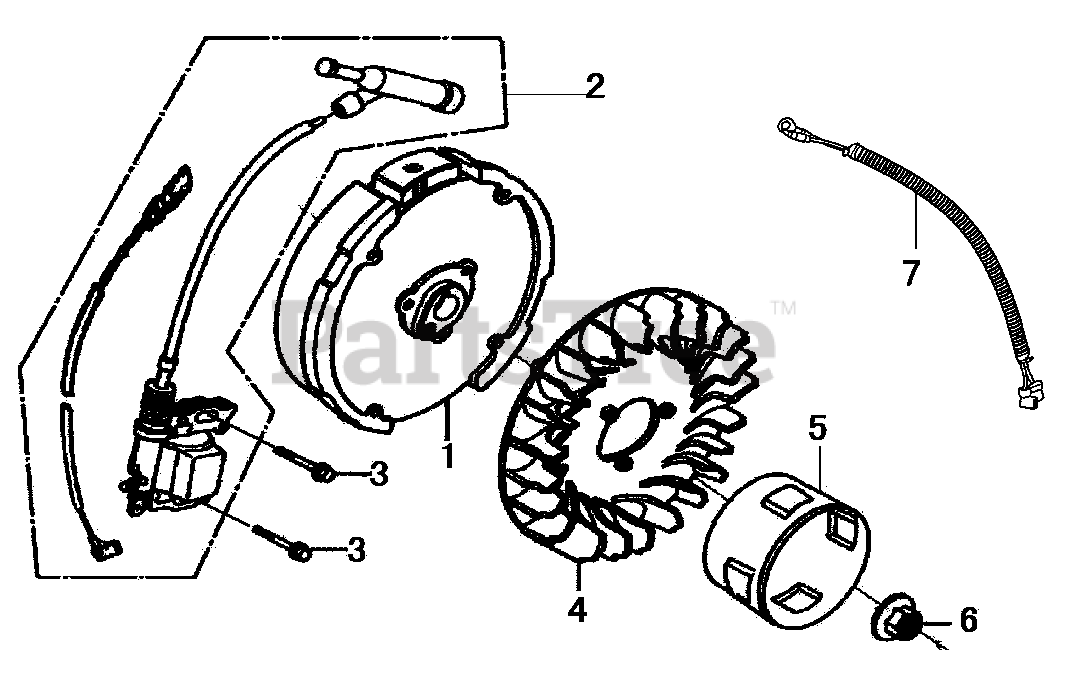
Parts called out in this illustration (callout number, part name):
2	IGNITION COIL ASSEMBLY
3	FLANGE BOLT (M6*25)
4	COOLING FAN
5	STARTER PULLEY
6	SPECIAL NUT
7	STOP SWITCH CORD
